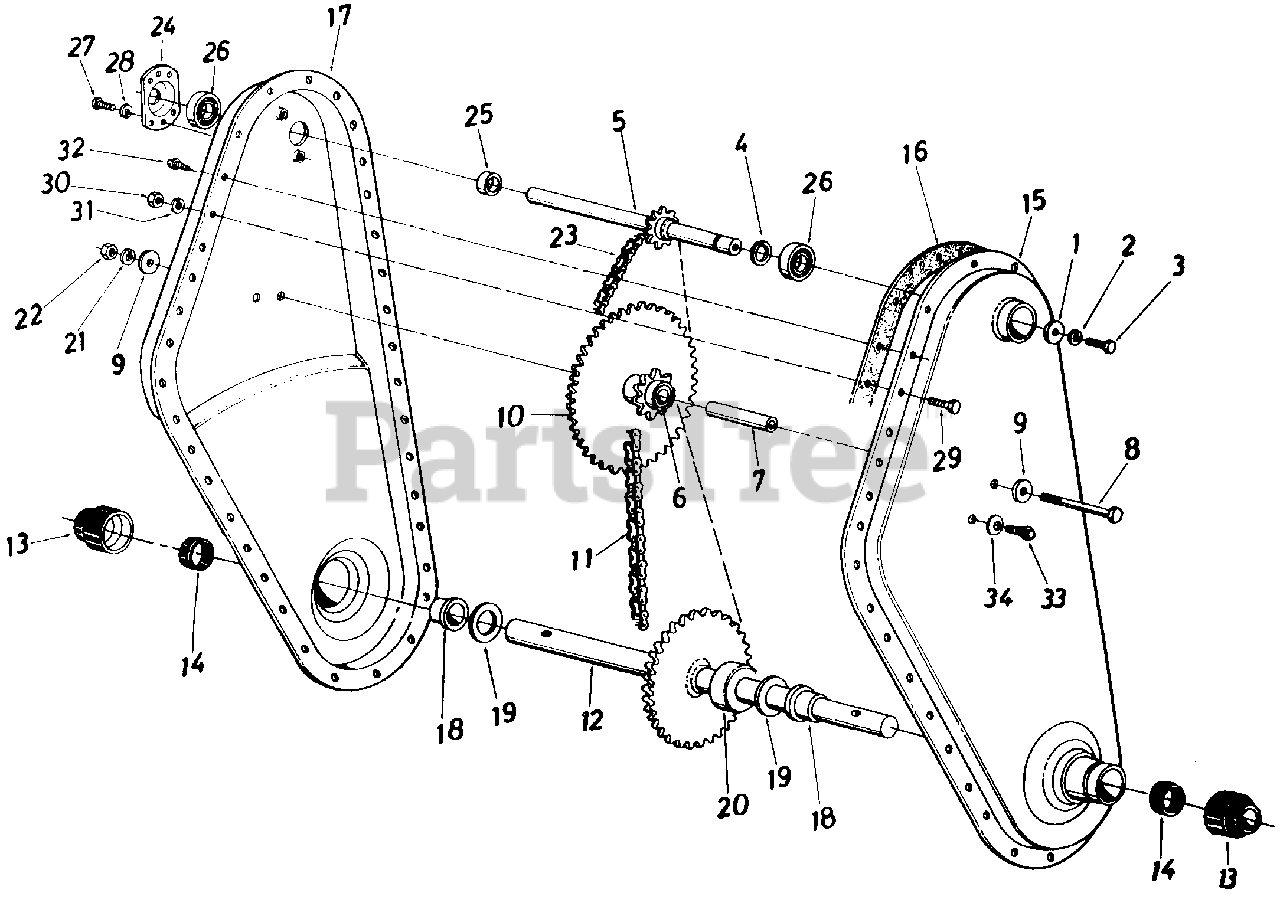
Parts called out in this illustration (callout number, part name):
1	Fl-Wash. 1/4" I.D. x .93" O.D. x . 1 20
2	L-Wash. 1/4" I.D.
3	Hex Bolt 1/4-28 x .62" Lg. w/Patch
4	External Snap Ring 5/8" Dia.
5	Input Shaft Ass'y.
6	Bearing 5/8" I.D. x 3/4" O.D. x 1.860" Lg.
7	Sprocket Hub Tubing 3/8" I.D. x 5/8" O.D. x 1.90
8	Hex Bolt 3/8-24 x 2.75" Lg.
9	Fl-Wash. 3/8" I.D. x 1.25" O.D. x .10
10	Sprocket Ass'y.
11	#50 Chain 5/8" Pitch x 46 Links Endless
12	Tine Shaft Ass'y.
13	Dust Cup
14	Seal Ring Single Lip, Springless
19	Fl-Thrust Wash. 1.0" I.D. x .03 Thk.
20	Step Spacer
21	L-Wash. 3/8 I.D.
22	Hex Nut 3/8-24 Thd.
23	#35 Chain 3/8" Pitch x 52 Links Endless
24	Bearing Housing 1.38" I.D.
25	Spacer
26	Ball Bearing .625" I.D. x 1.38" O . D . x .437
27	Hex Wash. SF-Tap Scr. 1/4-20 x .50" Lg.
28	L-Wash. 1/4" I.D.
29	Hex Bolt 5/16-18 x .75" Lg.
30	Hex Nut 5/16-18 Thd.*
31	L-Wash. 5/16" I.D.
32	Hex Wash. SF-Tap Scr. 1/4-20 x .50" Lg.
33	Hex Wash. Hd. Tap Scr. 1/4-20 x .38" Lg.
34	Bell-Wash. .265" I.D. x .75" O.D.
